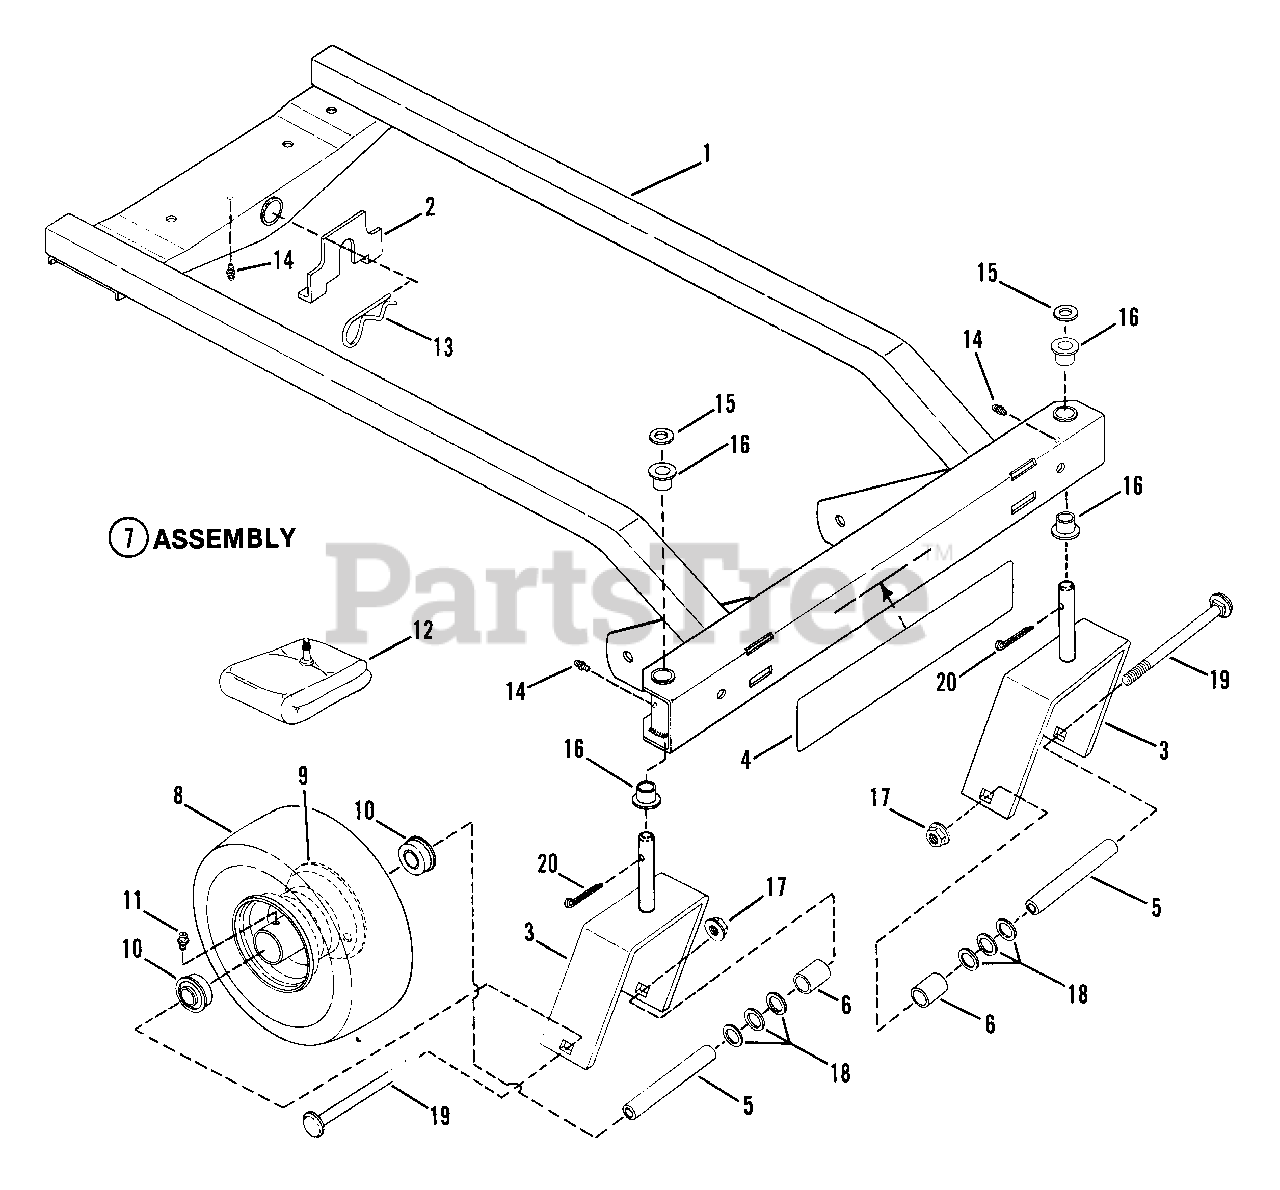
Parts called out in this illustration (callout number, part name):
1	FRAME, Front
3	CASTER
4	DECAL-SNAPPER
5	TUBE, Caster
6	SPACER, Axle 1.00 OD X .758 ID X 1.00 L
7	ASSEMBLY, Tire & Rim
8	TIRE, 4.10/3.50 x 4
9	RIM, (For 4.10/3.50x4 Tire)
10	BEARING, Ball
11	FITTING, Lube
12	TUBE, Inner
13	PIN, Hair
14	FITTING, Lube
15	WASHER, Flat, 3/4"
16	BUSHING
17	NUT, 1/2-13 Hex Flange Lock
18	WASHER
19	BOLT, 1/2-13 x 5-1/2" SSNC
20	COTTER-PIN, 5/32 x 1"
